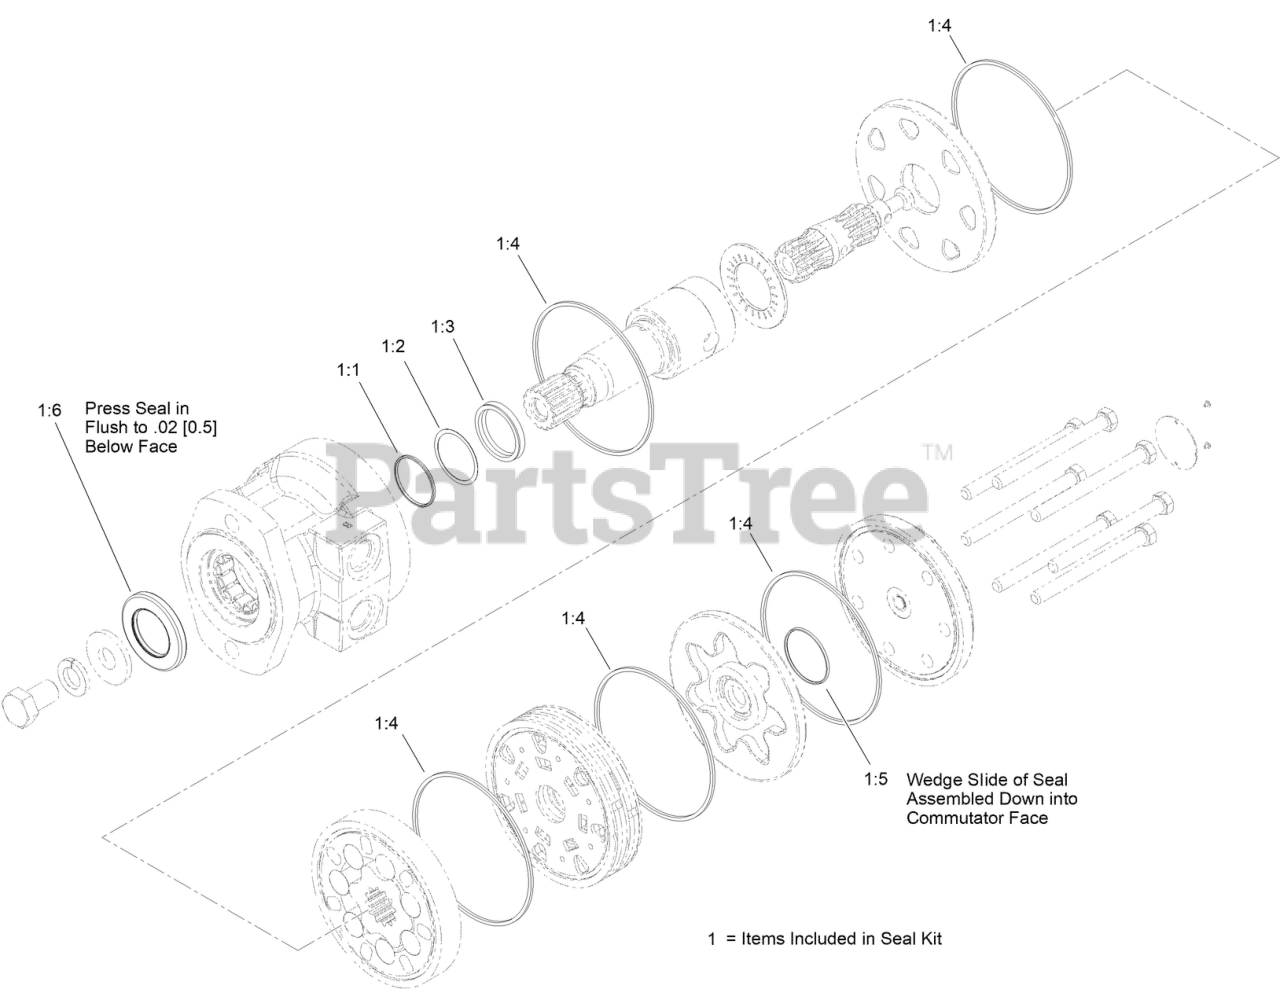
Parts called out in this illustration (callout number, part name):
1	SEAL KIT
1:1	Ring-Back Up
1:2	Washer-Back Up
1:3	SEAL-Shaft
1:4	Seal-Ring
1:5	Seal-Commutator
1:6	Seal-Dirt and Water
